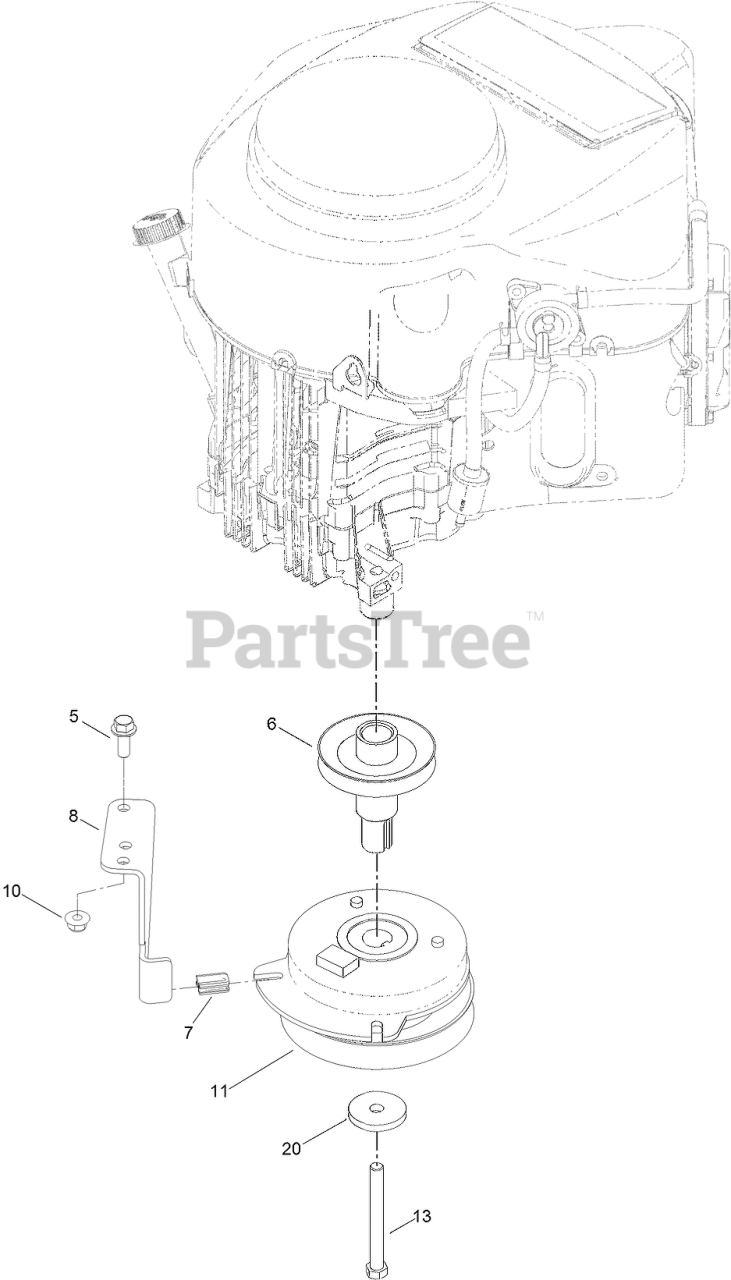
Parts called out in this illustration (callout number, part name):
5	SCREW-HHF
6	PULLEY-ENGINE
7	ISOLATOR-CLUTCH
8	STOP-CLUTCH
10	NUT-HF, NI
11	CLUTCH-PTO
13	SCREW-HH
20	WASHER-CLUTCH
